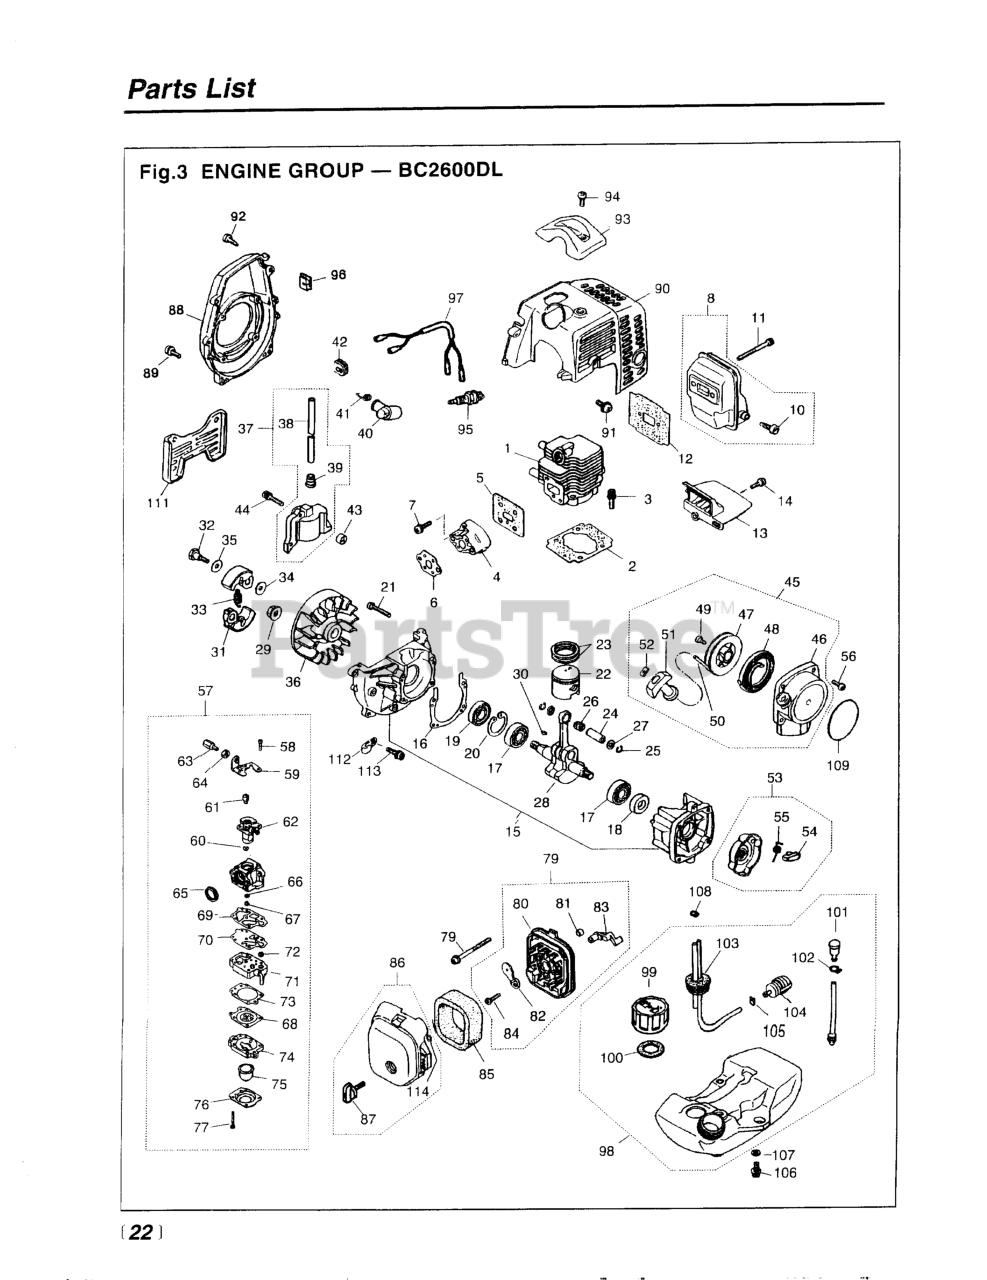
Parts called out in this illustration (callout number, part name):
1	CYLINDER
3	BOLT, M5 X 22
4	INSULATOR (USE -13163)
7	SCREW, M5X20 (RPLS.1400-75510)
8	MUFFLER ASSY (RPLS 5501- )
10	ARRESTER (RPLS 5850-15140)
11	BOLT, M5 x 50
12	GASKET, MUFFLER
14	SCREW, M4 X 16
15	CRANKCASE
17	BEARING
18	SEAL, OIL (RPLS 1100-21210)
19	SEAL, OIL (RPLS 1140-21220)
20	RING, SNAP, M28 x 1.2
21	BOLT, M5 X 30
22	PISTON
23	RING, PISTON
24	PIN, PISTON
25	RING, SNAP (RPLS 1101-41320)
27	WASHER
28	CRANKSHAFT (RPLS 1850-42000)
30	KEY
31	SHOE (RPLS 1100-51114)
32	BOLT
33	SPRING, CLUTCH (RPLS-51220)
34	WASHER, FLAT (USE 182303)
37	COIL ASSY (RPLS 5500-71200)
38	CORD
39	CAP
41	SPRING
42	GROMMET
43	SPACER (RPLS -71260)
44	BOLT
45	RECOIL ASSEMBLY
46	CASE
47	REEL
48	SPRING, SPIRAL
49	SCREW (RPLS -75150)
51	KNOB
52	PLATE, STOPPER
53	PULLEY ASSY (RPLS -75210)
54	RATCHET (RPLS 1850-75220)
55	SPRING, RETURN
56	SCREW, M4 X 16
57	CARBURETOR (WYJ-117)
58	SCREW
60	RING
61	SWIVEL
62	VALVE ASSY
63	SCREW, CABLE ADJUSTER
64	NUT, CABLE ADJUSTER
65	RING, PACKING
66	RING, O
68	DIAPHRAGM (USE 4810-81260)
69	GASKET, PUMP
70	DIAPHRAGM
71	BODY, PUMP
73	GASKET, DIAPHRAGM
74	BODY, PURGE
75	PUMP, PRIMING
76	COVER, PUMP
77	SCREW
78	SCREW, M5 X 55
79	BODY-A (RPLS -82101)
81	SLEEVE
82	PLATE, CHOKE (RPLS-82130)
83	LEVER, CHOKE
84	SCREW (REPLACES 50030272)
85	ELEMENT
87	KNOB (RPLS -82220)
88	COVER, FAN (RPLS-31110)
89	SCREW, M5X20 (RPLS.1400-75510)
91	SCREW, M5 x 12
92	SCREW, HOUSING
93	GUARD, PLUG
94	SCREW,M5 X 14 (RPLS 1400-15510
97	CORD COMP (RPLS -73200)
99	CAP (RPLS -85200)
100	PACKING
103	PIPE COMPLETE
104	FILTER (RPLS 1850-85300)
105	CLIP (REPLACES 2841-31280)
106	SCREW
107	SCREW W/ WASHER
108	CLIP
109	LABEL, RECOIL (RPLS -91120)
111	STAND
112	CLAMP
113	SCREW,M5 X 14 (RPLS 1400-15510
114	RING
